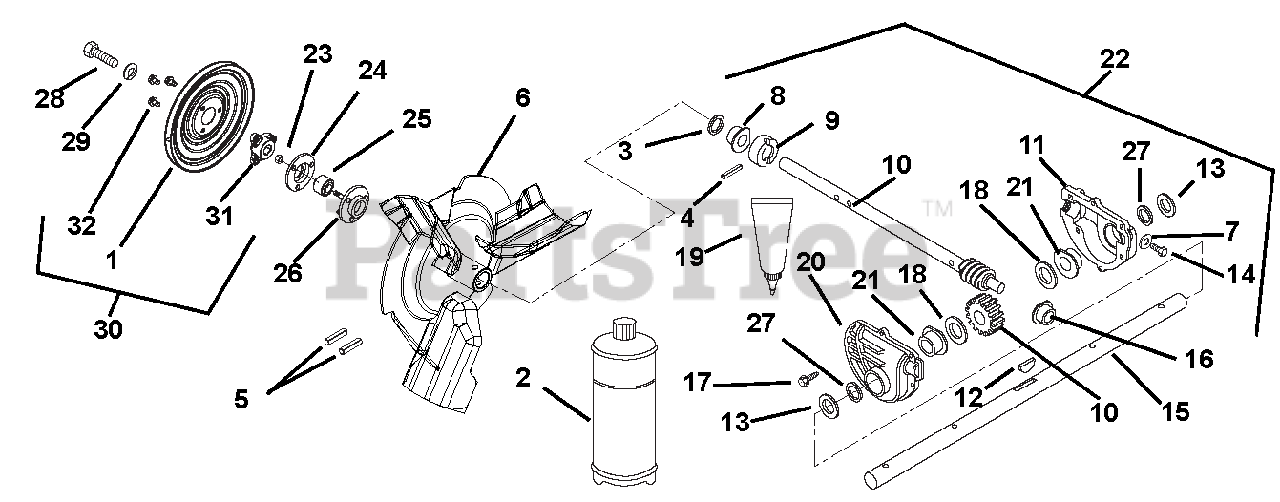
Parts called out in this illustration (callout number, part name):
1	PULLEY,SPIN FORM SINGLE GROOVE
2	ARIENS L3 LUBE, 8 OZ BOTTLE
3	SEAL-OIL.748X1.378X.276 RBR OD
4	@PIN-GRV .188X1.25 TP E ALLOY
5	PIN-ROLL .250X1.75
6	IMPELLER, COMPACT 12" 3-BLADE
7	WSHR-FIBER .437X.656X.032
8	BSHG-FLG .750X1.000X.750X1.250
9	THRUST COLLAR, .75" ID
10	SHAFT AND WORM GEAR ASSEMBLY
11	GEARCASE CASTING, MACHINED LH
12	KEY-WDRF .19X.63 HRD #61
13	@WSHR-FL-STL.812X1.50X.135YWZC
13	BSHG-SLV .75X1.12X1.062 NYL BK
14	SCR-TAP .38-16X.75 ROLOK YZ WX
15	SHAFT, RAKE - 20" (.750 DIA)
15	SHAFT, RAKE - 22" (.750 DIA)
15	SHAFT, RAKE - 24" (.750 DIA)
15	SHAFT, RAKE - 26" (.750 DIA)
16	BSHG-FLG .502X1X.750
17	@SCR-TAP .25-20X1.00 HWH TR YZ
18	WSHR-FL-STL.755X1.375X.062YWZC
19	LOCTITE 518 GASKET--6ML TUBE
20	GEARCASE CASTING, MACHINED RH
21	BSHG-FLG .753X1.127X.500X1.501
22	GEARCASE, 24" ALUM, SMALL CD
22	GEARCASE, 20" ALUM, SMALL CD
22	GEAR CASE ASSEMBLY - 22" ALUM.
22	GEAR CASE ASSEMBLY - 26" ALUM.
23	@NUT-LK-CTR .25-20 YWZC
24	BEARING FLANGE
25	BRG-BALL .750X1.750X.50
26	BEARING FLANGE
27	SEAL-OIL .750X1.375X.250
28	BLT-HEX .31-24X.75 YWZC GR5
29	WSHR-LK .312X.097 HVY YWZC
30	PULLEY WITH HUB
31	PULLEY HUB, BOLT-ON D-BORE .75
32	@SCR-TAP .31-18X.50 HWH TR YWZ
